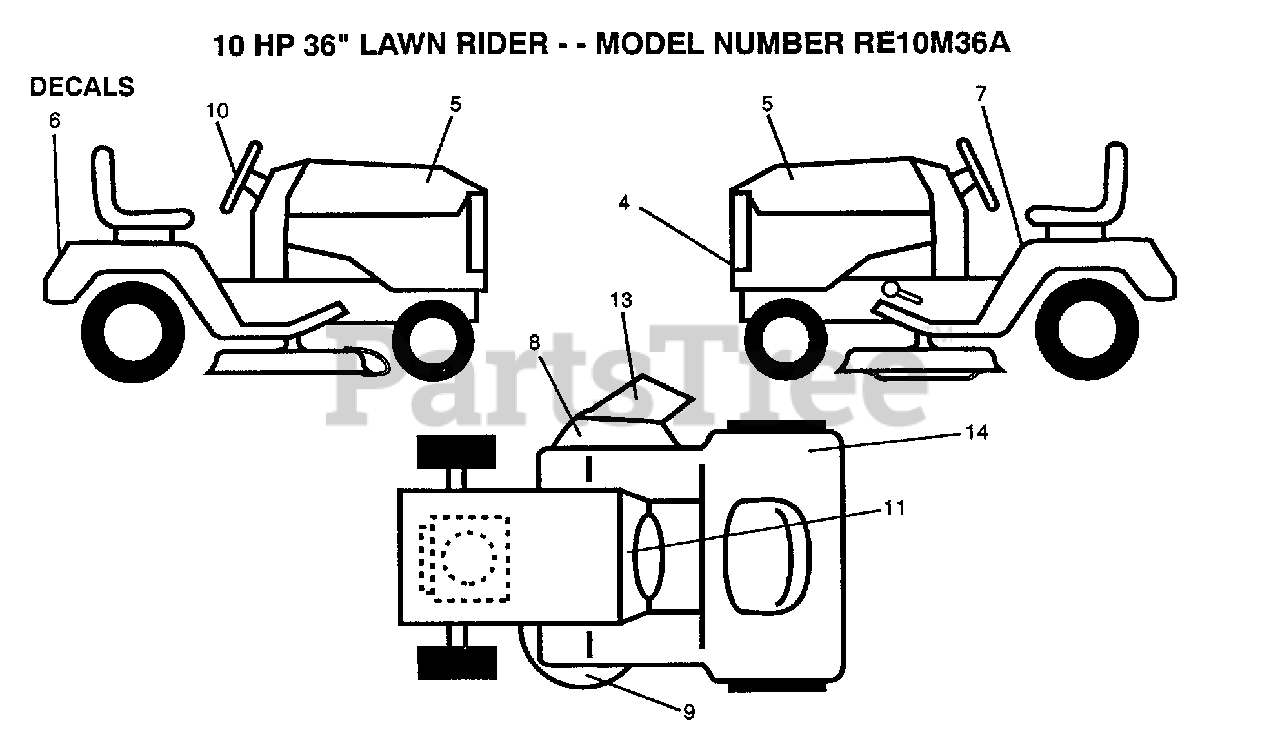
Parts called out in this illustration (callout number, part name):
4	GRILL DECAL
5	DECAL, HP HOOD
6	FENDER DECAL
7	DECAL CAUTION
8	DECAL WARNING
9	DECAL YT
10	"DECAL,STR WHL"
13	DECAL WARNING
